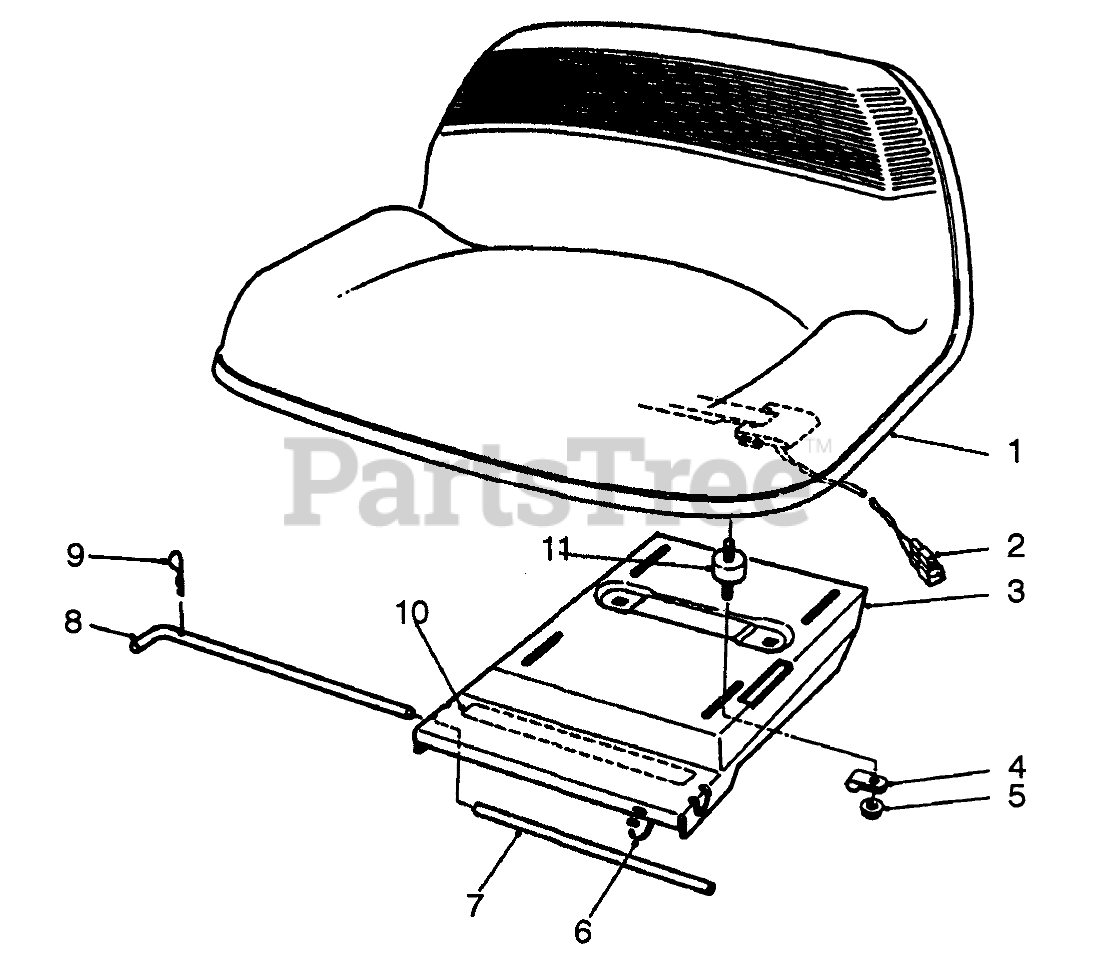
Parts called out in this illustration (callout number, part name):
1	Seat
2	SWITCH-SEAT
3	Base-Seat
4	CLAMP
5	NUT-HF
6	TIE-CABLE
7	TUBE-SEAT
8	ROD-SEAT BASE
9	PIN-COTTER
10	DECAL
11	ISOLATER-SEAT
